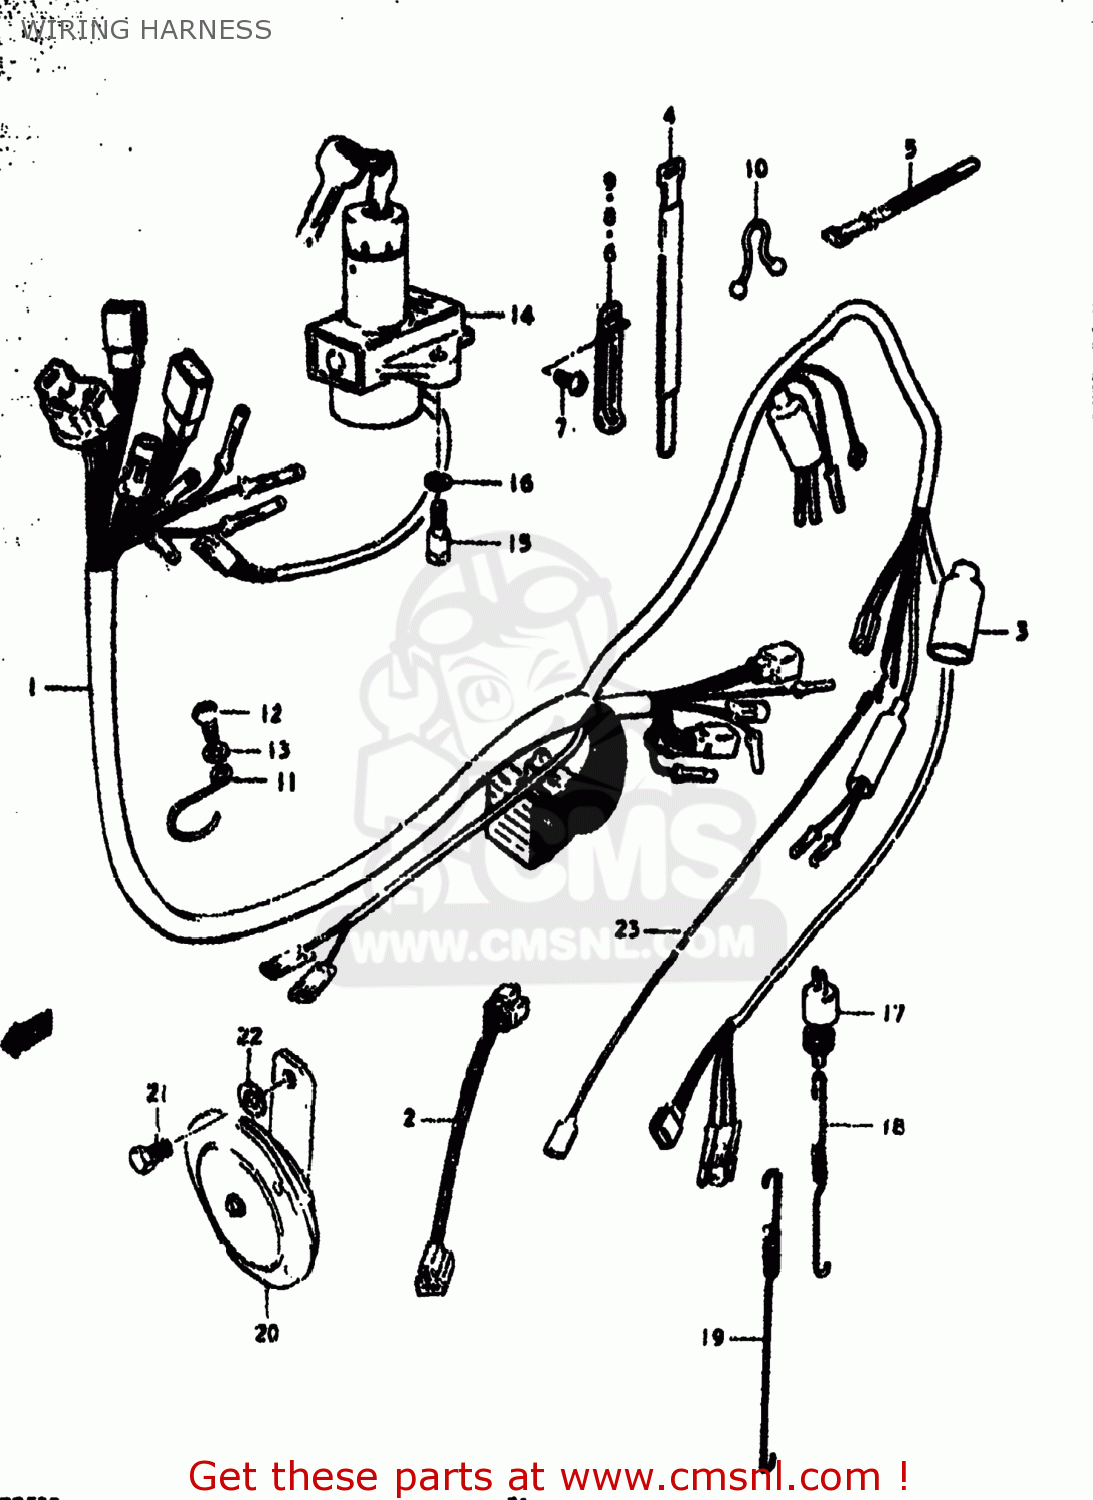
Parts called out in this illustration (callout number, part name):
1	HARNESS,WIRING
2	WIRE
3	COVER,WIRING HARNESS
4	CLAMP
5	CLAMP(L:120)
6	CLAMP
7	CLAMP
8	SCREW
9	CLAMP
10	CLAMP
11	CLAMP
12	GUIDE,WIRING HARNESS
13	SCREW 6X12
14	LOCK ASSEMBLY,STEERING
15	BOLT
16	BOLT
17	LOCK WASHER
18	SWITCH ASSY,BRAKE LAMP
19	SPRING
20	SPRING
21	HORN ASSY
22	BOLT 8X12
23	WASHER
24	WIRE
